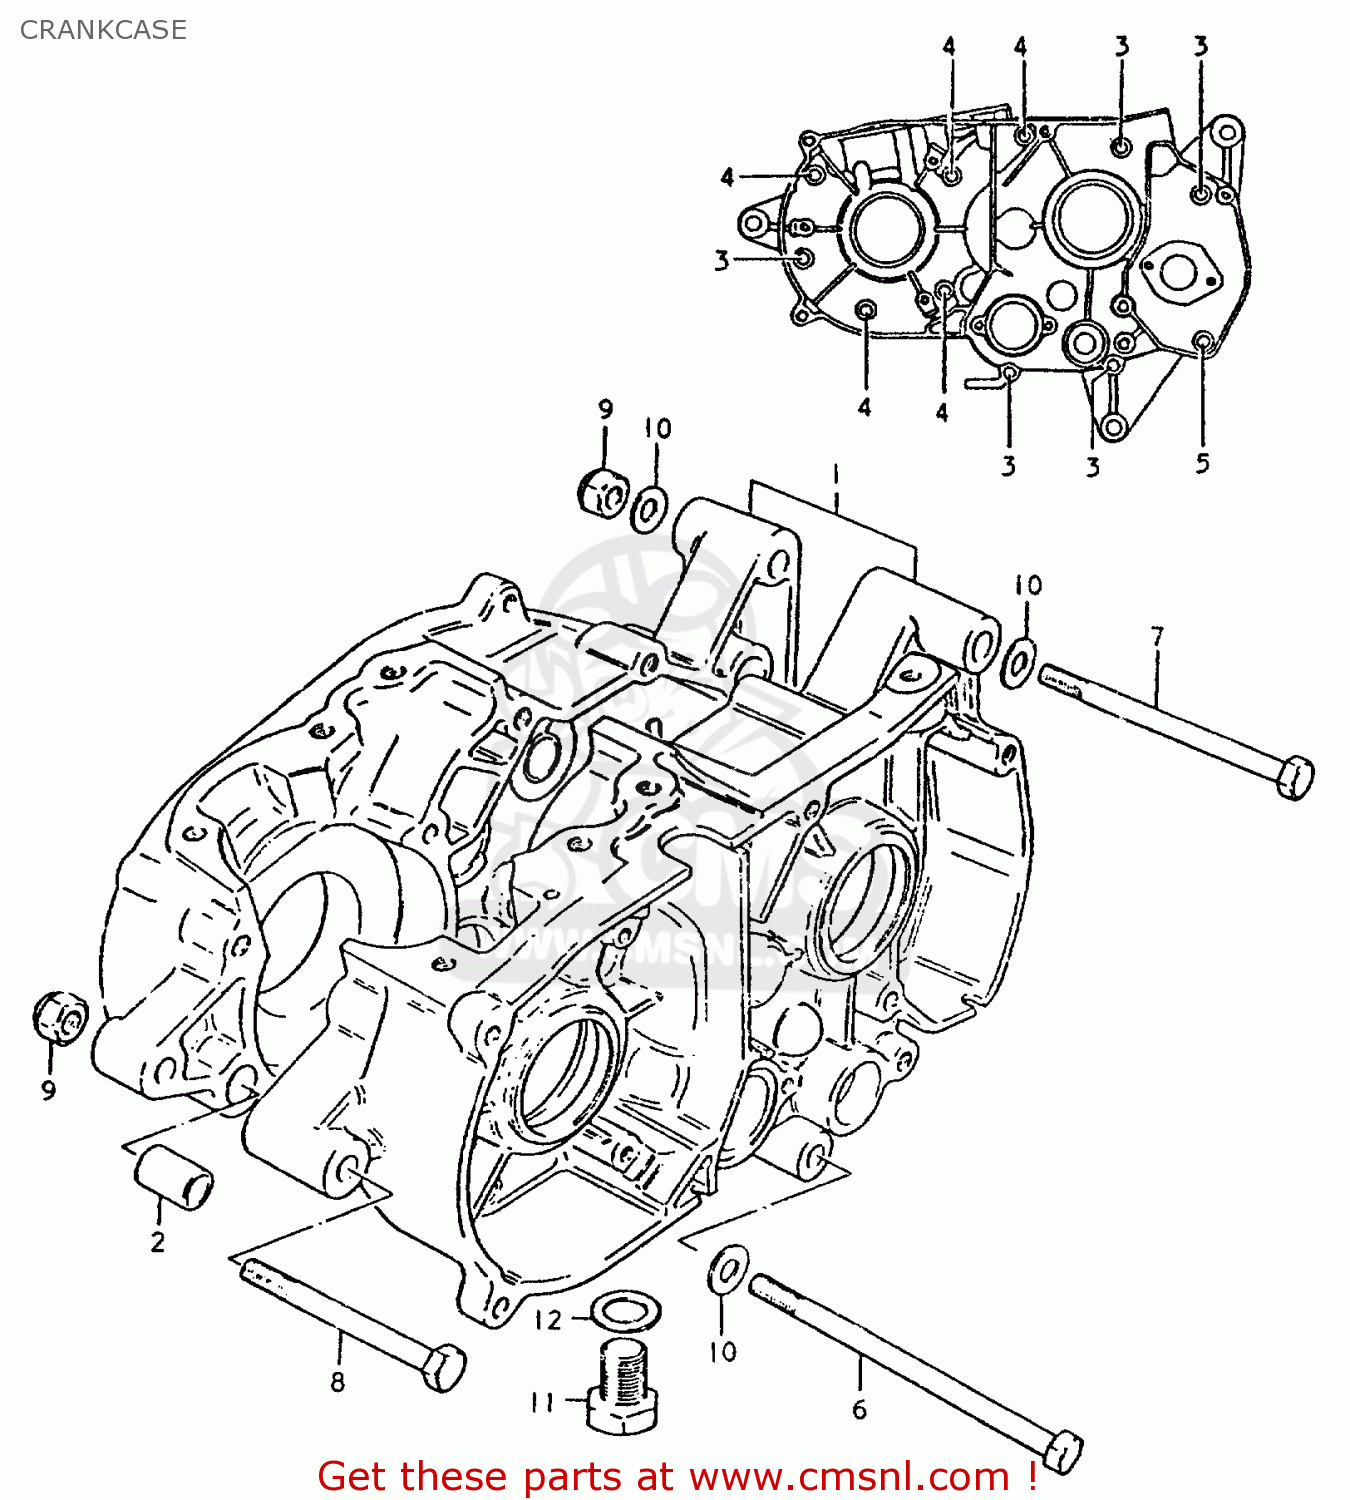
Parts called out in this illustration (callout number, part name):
1	CRANKCASE SET
2	PIN
3	SCREW (6X45)
4	SCREW (6X35)
5	SCREW
6	BOLT
7	BOLT
8	BOLT 8X75
9	NUT
10	WASHER
11	BOLT 10X20
12	GASKET(10X14X3.6) (NAS)
